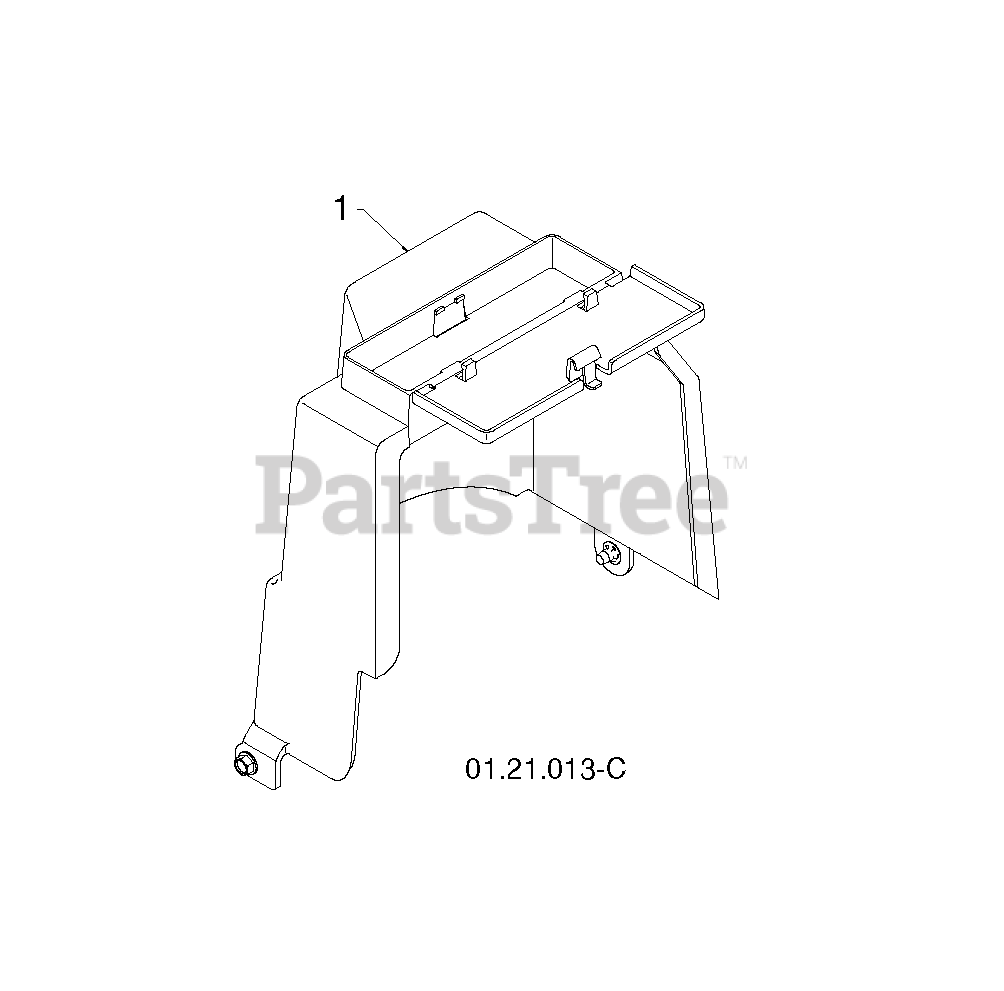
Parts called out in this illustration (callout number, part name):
1	BELT.V.IMPELLER
2	V-BELT TRACTION 34.25
3	ARM.IDLER.BRAKE.
4	PULLEY.W/SPACER.2.75
5	NUT.FLANGE.HEX.5/16X18.BLACK
6	HEX BOLT
7	RP BRACKET.IDLER.PIVOT
8	BOLT.5/16HEX.WHS.HD
9	BOLT.SHOULDER.1/2X12
10	NUT.LOCK.5/16-18
11	ARM, IDLER
12	PULLEY.W/SPACER.2.25
13	BOLT.5/16-18X1-1/4 FULL.THREAD
14	STEEL WASHER
15	NUT.71038.31-18.HEX.NYLOCK
16	SCREW, HEX HD 3/8-24 X 1-3/8
17	WASHER, FLAT 3/8
18	PULLEY.IMPELER.
19	PULLEY.ENG.TRACTION
21	LOCKWASHER
22	BELT.GUIDE.RH
23	WASHER EXT TOOTH LOCK 5/16
24	RP BUSHING, IDLER PIVOT
